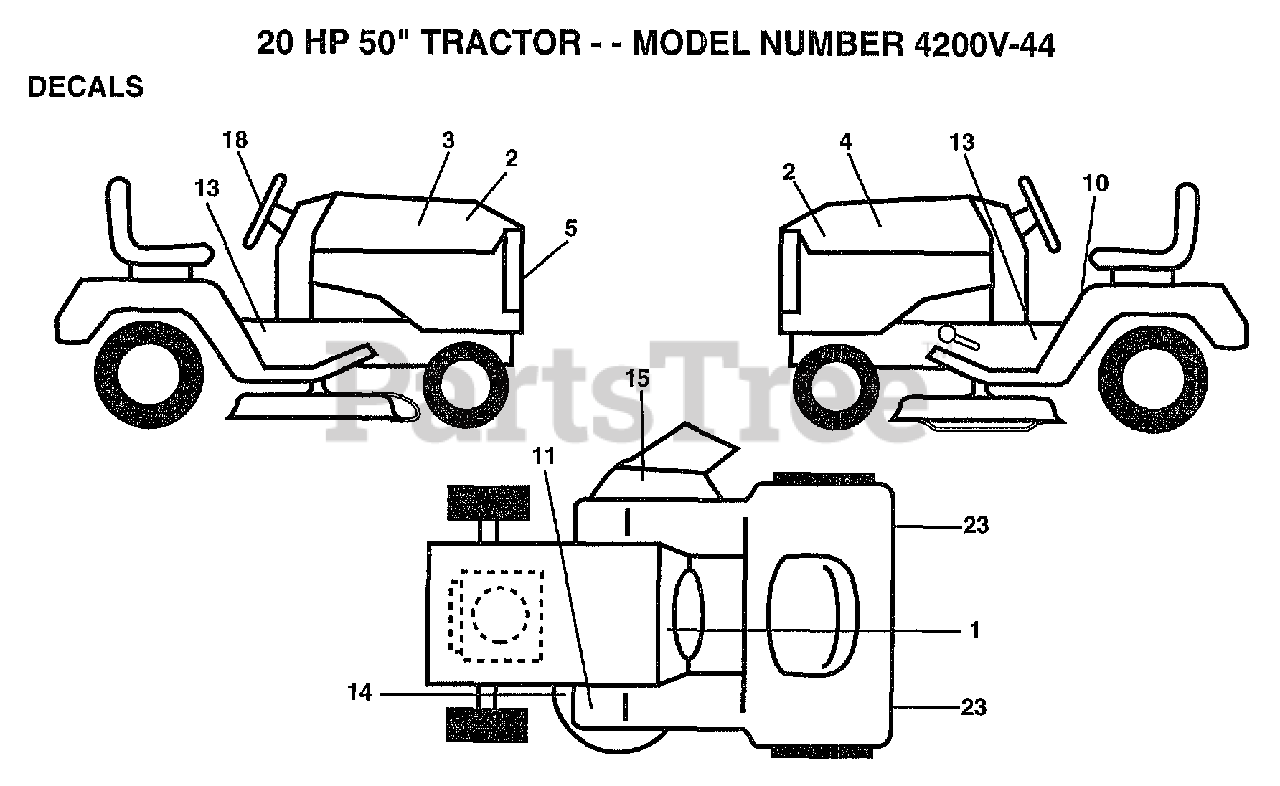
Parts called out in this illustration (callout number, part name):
1	DECAL.DASH.INST.
2	NAMEPLATE LOGO
4	HOOD DECAL LH
5	GRILL DECAL
10	DECAL
13	DECAL.CHASSIS
14	"DECAL.V.BELT.44"""
15	"DECAL, WARNING"
23	REFLECTOR-TAIL YT
